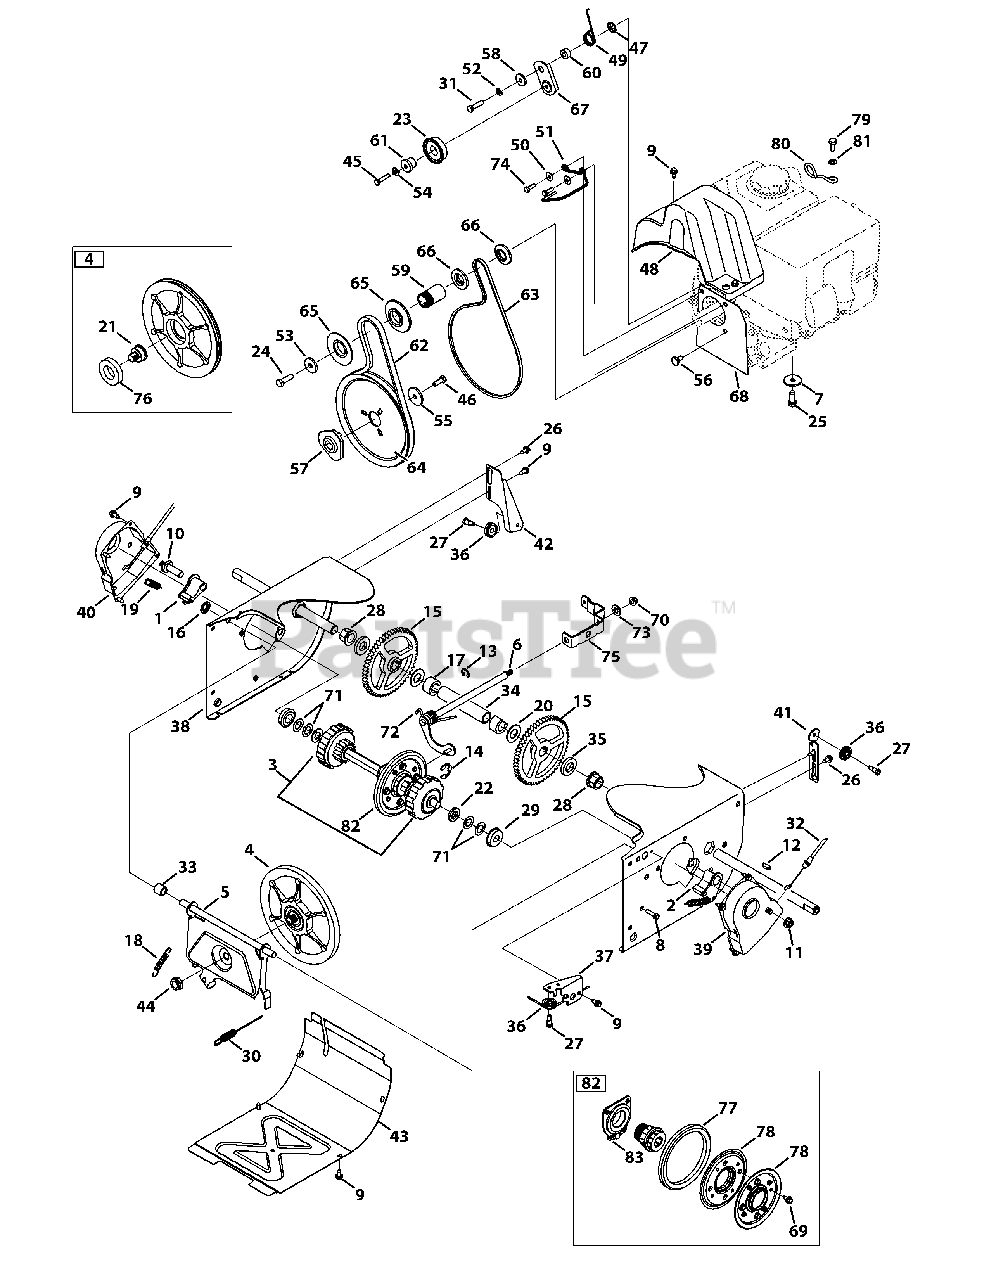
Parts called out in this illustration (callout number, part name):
1	Dogg Assembly, RH
2	Dogg Assembly, LH
3	Drive Shaft Assembly
4	Friction Wheel Disc Assembly
5	Friction Wheel Support
6	Rod Shift Assembly
7	Washer, Flat, .38 x 1.38
8	Screw, 1/4-20 x 1.000
9	Screw, 1/4-20 x .625
10	Actuator Shaft
11	Nut, Flangelock, 3/8-16
12	Hi-Pro Key, 3/16 x 3/4 DIA
14	Retainer Ring
16	Nut, Speed, .500
17	Spacer, .76 x .75
18	Extension Spring, .380 x 2.500
19	Extension Spring, .500 x 1.71
20	Washer, Flat, .76 x 1.49
21	Friction Pin, Disc Bearing
22	Spacer, .68 ID x 1.25 OD x .20
23	Pulley Assembly
24	Hex Head Screw, 3/8-24 x 1.25
25	Taptite Sems Screw, 3/8-16 x 1.000
26	Screw, Shoulder, .368 x .113 x 1/4-20
27	C Screw, Shoulder, .340 x .335 x 1/4-28
28	Hex Flange Bearing, .75 ID
29	Ball Bearing, 17 x 40 x 12
30	Drive Clutch Cable
31	Hex Head Screw, 5/16-24 x 1.25
32	Steering Cable
33	Spacer, .508 x .75
34	Axle Support Tube
35	Spacer, Axle
36	Roller Cable
37	Auger Cable Guide Bracket
38	Wheel Drive Frame
39	Shaft Retainer, LH
40	Shaft Retainer, RH
41	Auger Clutch Cable Guide Bracket
42	Drive Clutch Cable Guide Bracket
44	Nut, Flange, 5/8-18
45	Taptite Screw, 1/4-20 x 1.250
46	Hex Head Screw, 5/16-24 x .875
47	Nut, Push-On, .25 DIA
48	Belt Cover, 4-Way lrg. block
49	Spring, Torsion, .850 x .333
50	Washer, Flat, .349 x .879
51	Belt Guide
52	Washer, Lock, 5/16
53	Washer, Flat, .45 x 1.5
54	Washer, Lock, 1/4
55	Washer, Flat, .34 x 1.50
56	Screw, Shoulder
57	Pulley Adapter, .75 DIA
58	Spacer, Shoulder, .3175 x .500
59	Spacer, .875 x 1.185
60	Spacer, .340 x .750
61	Spacer, Shoulder, .260 x .785
62	Auger Drive Belt, 4-Way lrg. block
63	V Belt, 3L x 36.64"
64	Auger Pulley, 8.1 x .5
65	Pulley, Half, 4L-V x 2.600
66	Pulley, Half, 3/8-V x 2.2
67	Drive Idler Bracket
68	Cover Plate, 4-Way lrg. block
69	Screw, 5/16-18 x .750
70	Nut, Flangelock, 5/16-18
71	Flat Washer, .67 x 1.174 x .02
72	Spring, Torsion, .750 x .968
73	Washer, Flat, .469 x .875 x .105
74	Hex Head Screw, 5/16-24 x 1.00
75	Speed Selector Shift Bracket
76	Ball Bearing, 30 x 55 x 13
77	Friction Wheel, 5.5 OD
78	Friction Wheel Plate
79	Hex Head Screw, 1.25 x 20
80	Cable Guide
81	Washer, Flat, .330 x .630
82	Friction Wheel Assembly
83	Bearing Assembly, Friction Wheel
